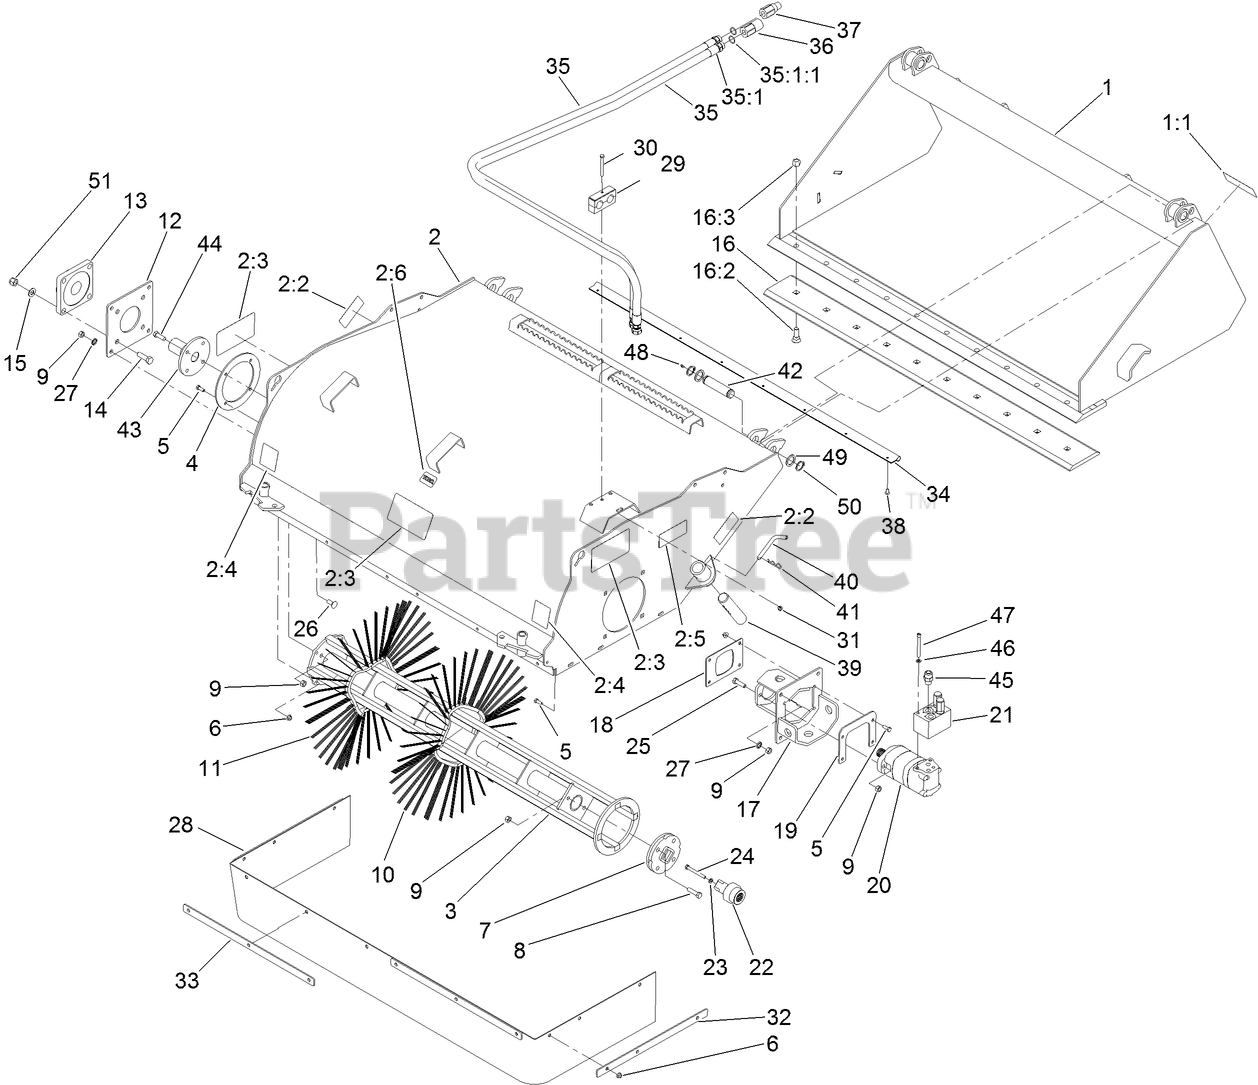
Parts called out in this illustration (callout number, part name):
1	PICK-UP BROOM BUCKET ASM
1:1	DECAL-CAPACITY
2	HOOD ASM
2:2	DECAL-WARNING, PINCH POINT
2:3	DECAL-DANGER
2:4	DECAL-WARNING
2:5	DECAL-WARNING
2:6	DECAL
5	SCREW-HH
6	NUT-HF, NI
7	FLANGE-DRIVE
8	SCREW-HH
9	NUT-HH
10	BRUSH-POLY
11	BRUSH-STEEL
12	PLATE-MOUNT, BEARING
13	BEARING-FLANGED
14	SCREW-HH
15	WASHER-FLAT
16	60in BROOM EDGE KIT
16:2	BOLT-PLOW
16:3	NUT-LOCK, NI
17	MOUNT-MOTOR
18	SEAL-MOTOR, RUBBER
19	RETAINER-SEAL
20	HYDRAULIC MOTOR ASM
21	MANIFOLD
22	ADAPTER-MOTOR
23	WASHER-LOCK
24	SCREW-HH
25	SCREW-HH
26	SCREW-CARR
27	NUT-PUSH
28	FLAP-RUBBER
29	CLAMP-HOSE
30	SCREW-HH
31	NUT-HF, NI
32	BRACKET-RETAINING, SIDE
33	BRACKET-RETAINING, FRONT
34	SEAL-RUBBER, REAR
35	HYD HOSE ASM
35:1	FITTING-STRAIGHT
35:1:1	O-RING
36	FITTING-ADAPTER
37	FITTING-ADAPTER
38	RETAINER
39	SHAFT-ADJUSTMENT
40	PIN-BENT
41	PIN-HAIR
42	PIN-PIVOT
43	PLATE-DRUM
44	SCREW-HH
45	FITTING-ADAPTER
46	WASHER-LOCK
48	FITTING-ZERK
49	WASHER-STEERING
50	RING-RETAINING, EXTERNAL
51	NUT-LOCK, NI
